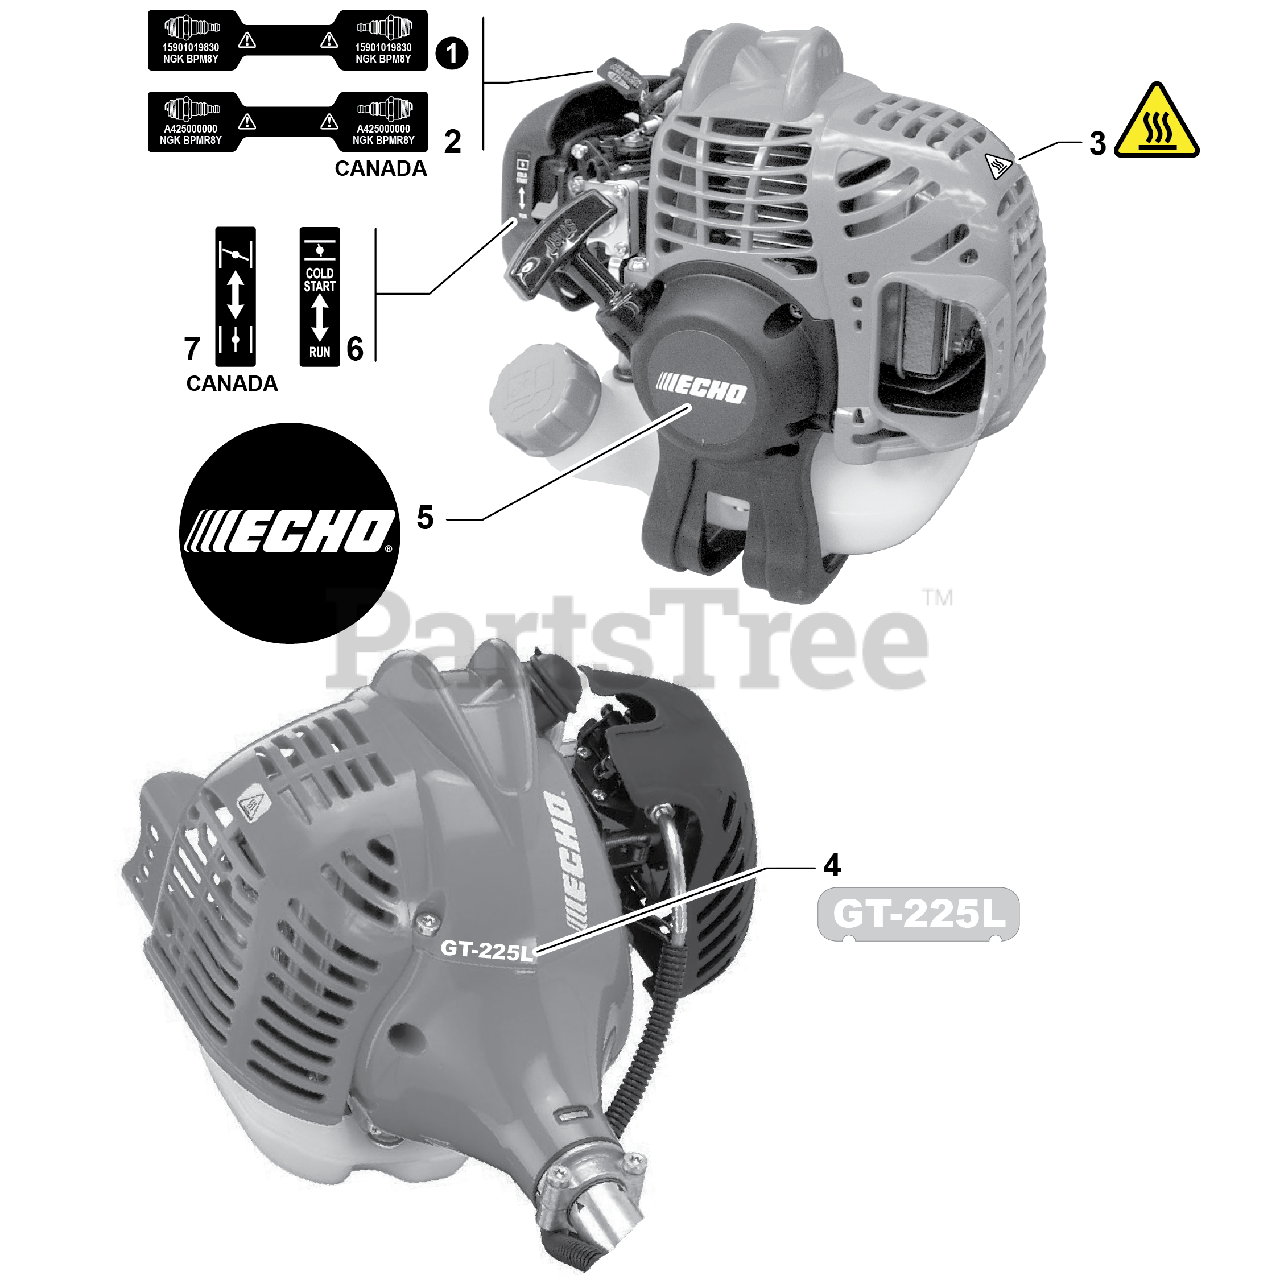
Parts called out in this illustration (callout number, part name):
1	LABEL, SPARK PLUG - BPM8Y
2	LABEL, SPARK PLUG - BPMR8Y
3	LABEL, CAUTION - HOT
4	LABEL, MODEL - GT-225L
5	LABEL, ECHO
6	LABEL, CHOKE
7	LABEL, CHOKE
